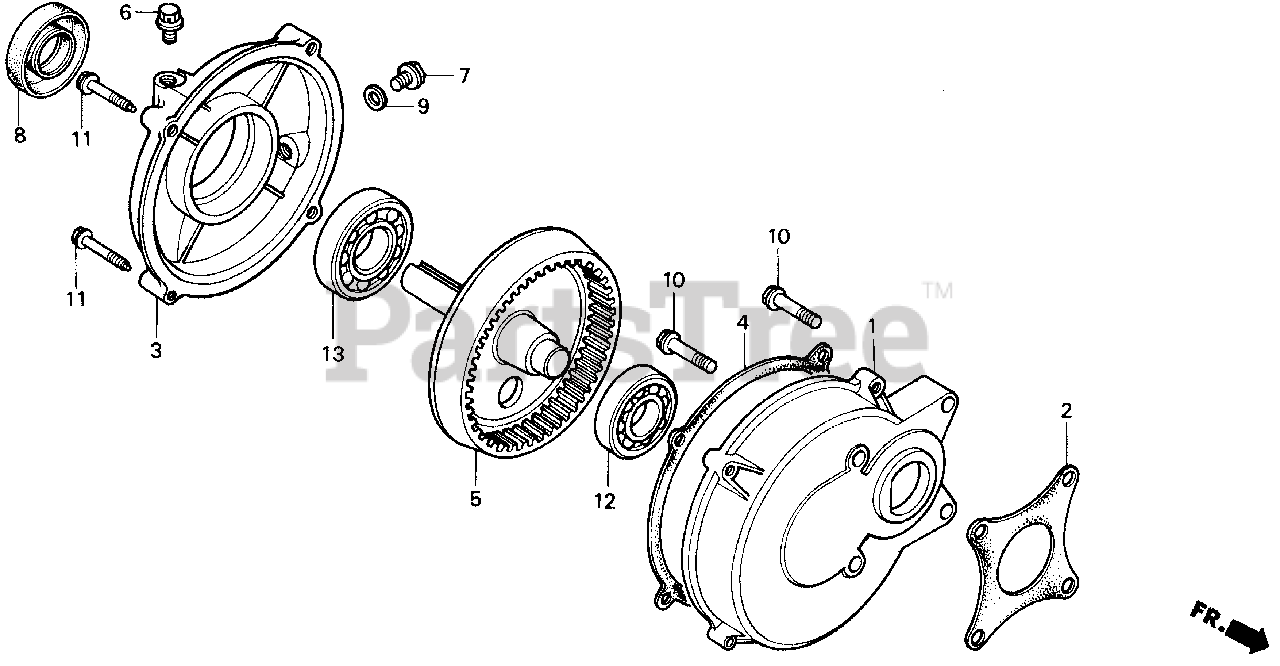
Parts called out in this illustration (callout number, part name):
1	CASE, REDUCTION
2	GASKET, REDUCTION CASE
3	COVER, REDUCTION
4	GASKET, REDUCTION COVER
5	SHAFT, P.T.O.
6	BOLT, BREATHING
7	BOLT, DRAIN PLUG
8	OIL SEAL (25X41X6)
9	WASHER, DRAIN PLUG (12MM)
10	BOLT, FLANGE (8X32)
11	BOLT, FLANGE (8X35)
12	BEARING, RADIAL BALL (6204)
13	BEARING, RADIAL BALL (6305)
